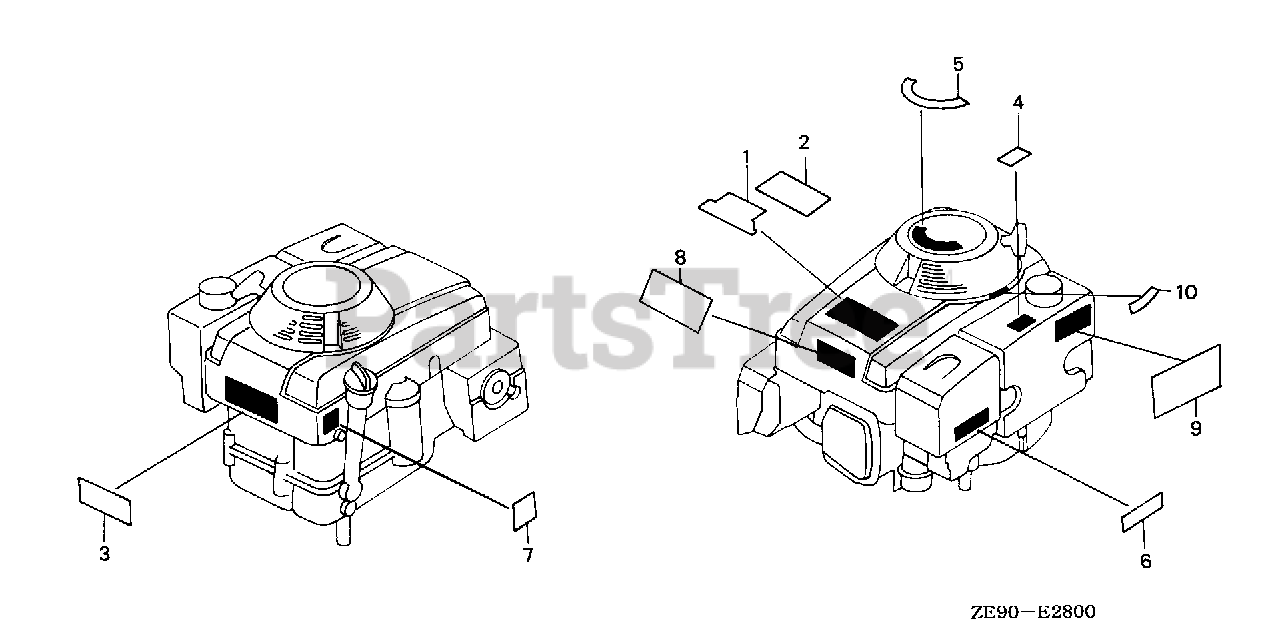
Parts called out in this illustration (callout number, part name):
2	EMBLEM, TOP COVER (OIL ALERT)
3	MARK, CAUTION (NOT AVAILABLE)
3	LABEL, EMBLEM (ENGLISH/FRENCH/GERMAN)
5	MARK, SALES POINT (A.C. SEL)
6	MARK, AIR CLEANER CAUTION
7	MARK, OIL CAUTION
